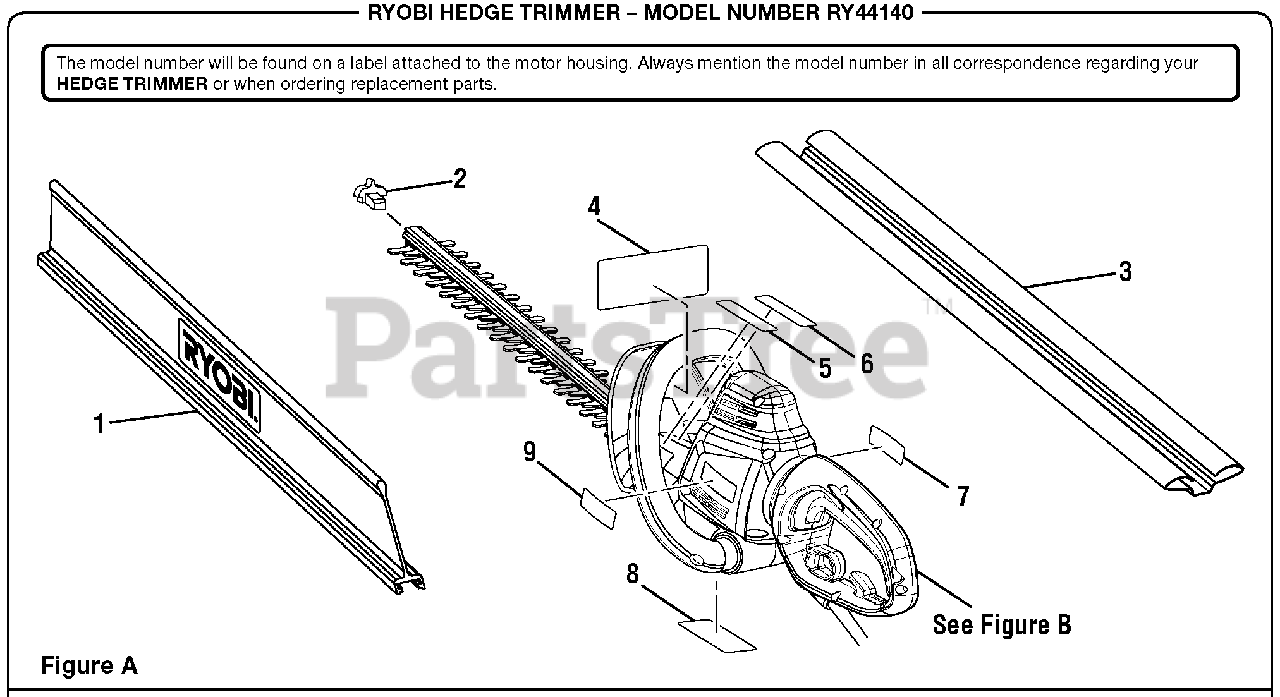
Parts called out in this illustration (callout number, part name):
1	Debris Deflector
2	Deflector Retainer
3	Blade Cover
4	Guard Warning Label
5	Icon Warning Label (Left)
6	Icon Warning Label (Right)
9	Replacement Parts Warning Label
